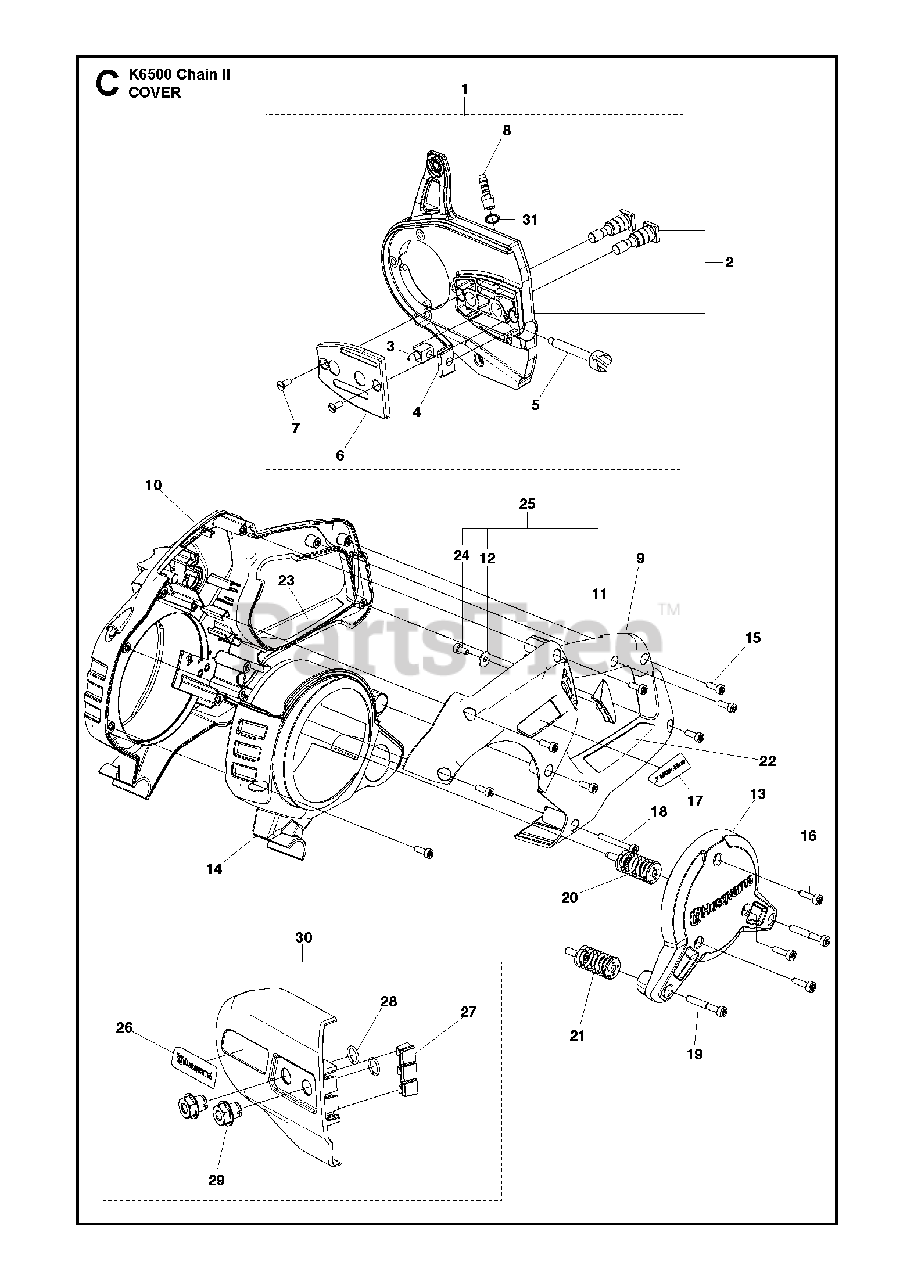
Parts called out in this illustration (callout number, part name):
7	SCREW SLCSFM
15	SCREW ITXSCT
16	SCREW ITXSCM
19	SCREW ITXSCM
20	ANTIVIBRATION ELEMENT
21	ANTIVIBRATION ELEMENT
24	SCREW ITXSCT
28	RETAINER RING
